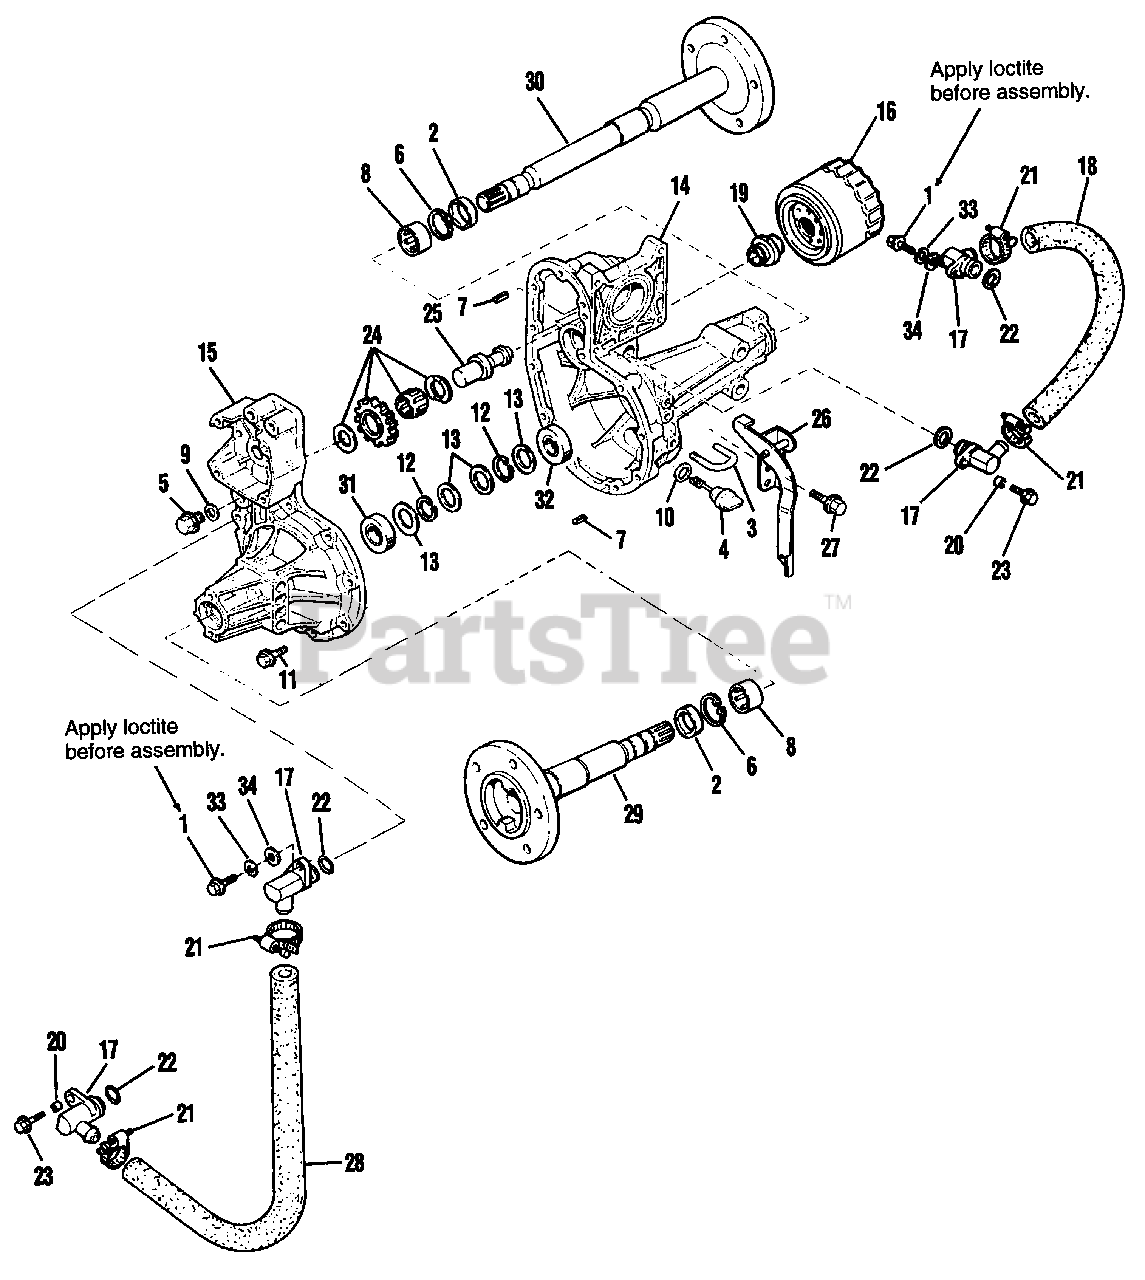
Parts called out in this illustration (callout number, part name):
8	BEARING, Needle
11	SCREW, Taptite
14	HOUSING, Transaxle, Right
15	HOUSING, Transaxle, Left
18	TUBE, Suction
21	CLAMP, Hose
24	GEAR SET, Idle
25	SHAFT, Idle
26	LEVER ASSY., Range
27	SCREW, Taptite
28	TUBE, Drain
29	SHAFT, Axle, Left
30	SHAFT, Axle, Right
33	LOCKWASHER
34	WASHER, Flat
